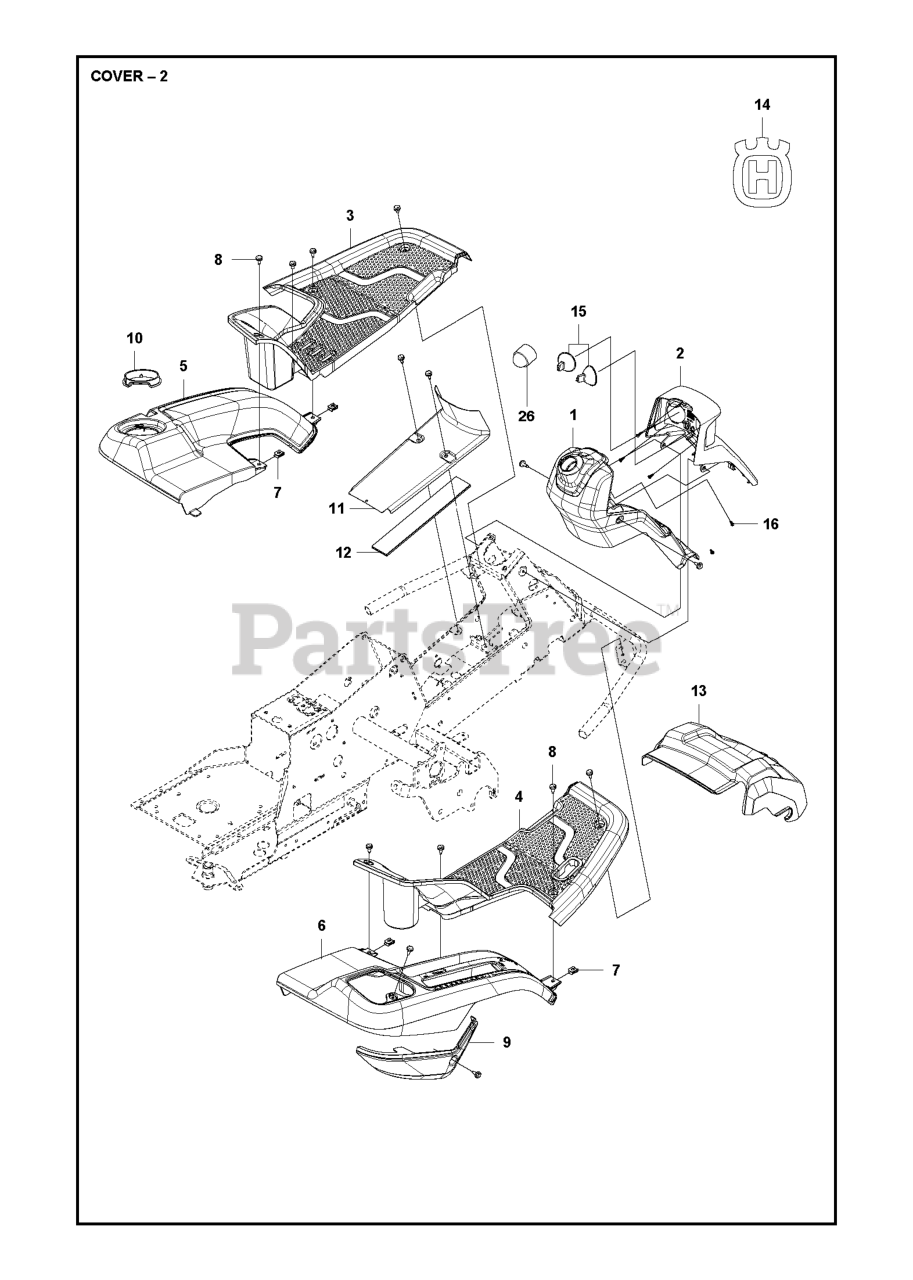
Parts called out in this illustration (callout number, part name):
2	COVER STEERING TOP ASSY HUSQVA
3	FOOT PLATE
4	FOOT PLATE
9	CONTROL COVER
10	LOCKING NUT
12	MAT COVER FRAME
26	PROTECTIVE COVER
